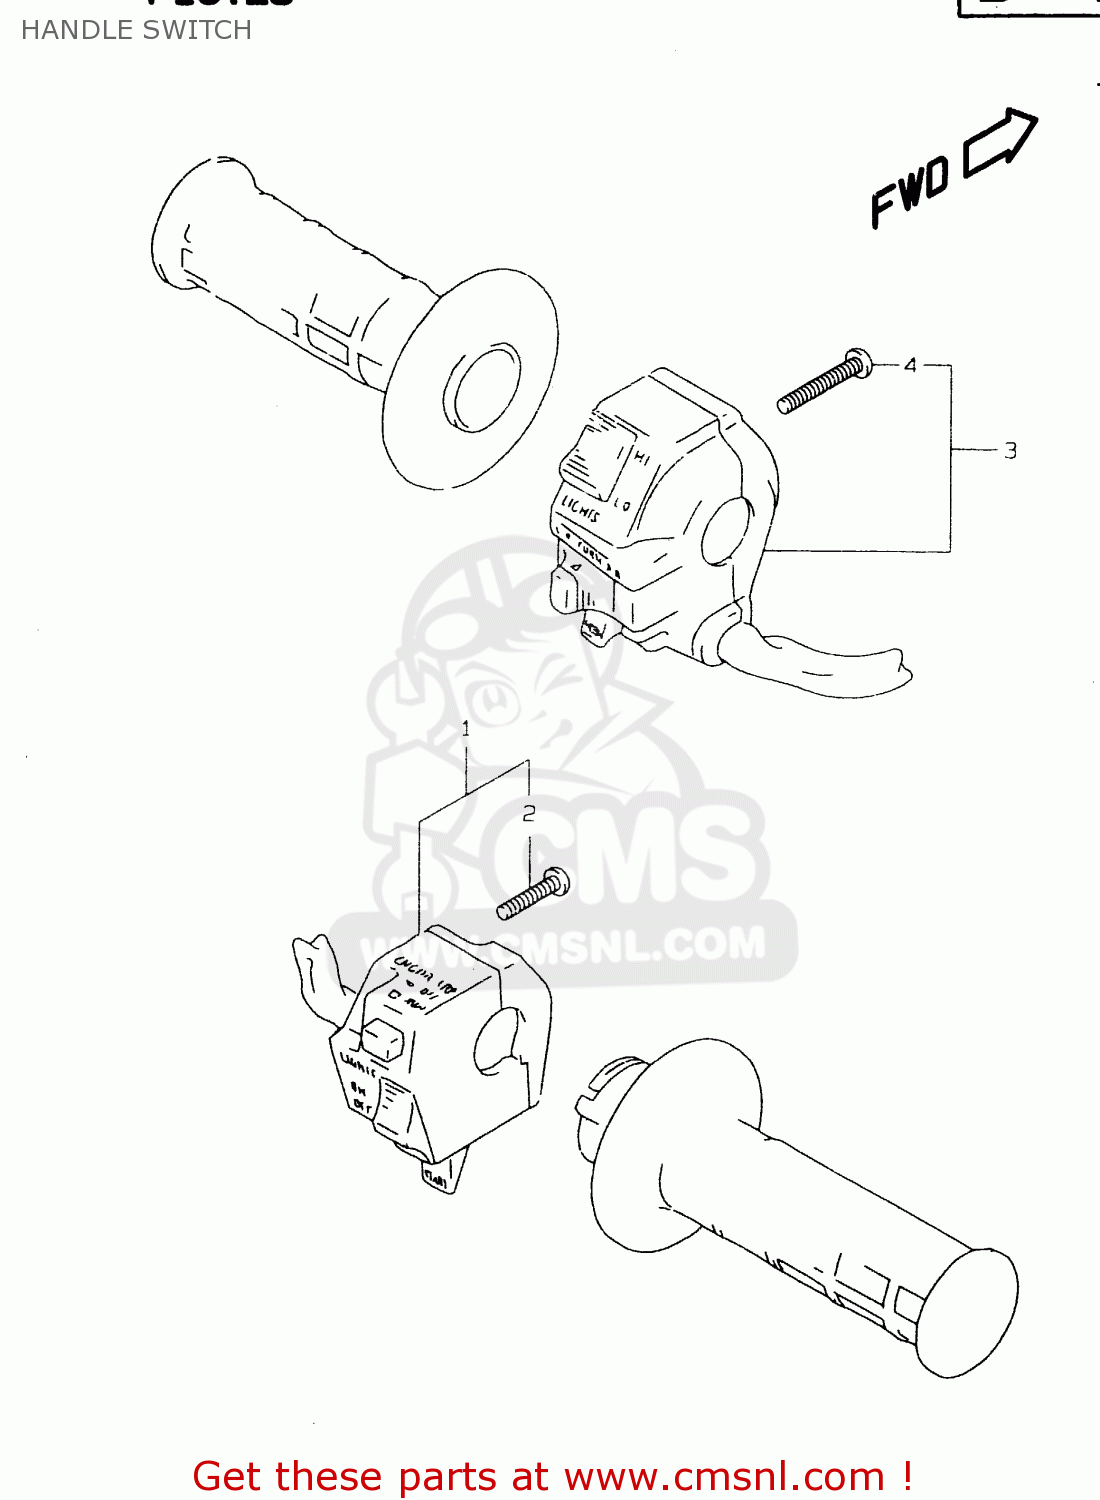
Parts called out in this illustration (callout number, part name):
1	SWITCH ASSY,HANDLE,R
2	SCREW(5X25)
3	SWITCH ASSY,HANDLE,L
4	SCREW
